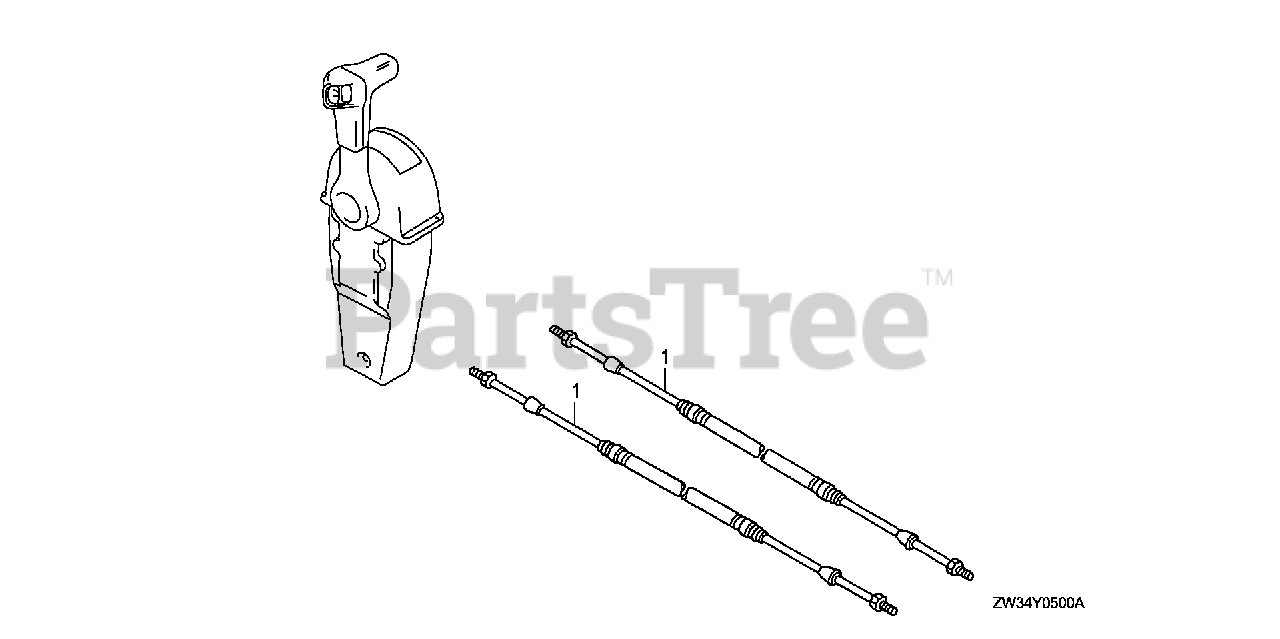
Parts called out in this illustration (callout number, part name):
1	CABLE, REMOTE CONTROL (10'') (LOW FRICTION)
1	CABLE ASSY., PUSH-PULL (33C-5FT)
1	CABLE, REMOTE CONTROL (11'') (LOW FRICTION)
1	CABLE ASSY., PUSH-PULL (33C-6FT)
1	CABLE, REMOTE CONTROL (12'') (LOW FRICTION)
1	CABLE ASSY., PUSH-PULL (33C-7FT)
1	CABLE, REMOTE CONTROL (13'') (LOW FRICTION)
1	CABLE ASSY., PUSH-PULL (33C-8FT)
1	CABLE, REMOTE CONTROL (14'') (LOW FRICTION)
1	CABLE ASSY., PUSH-PULL (33C-9F T)
1	CABLE, REMOTE CONTROL (15'') (LOW FRICTION)
1	CABLE ASSY., PUSH-PULL (33C-10FT)
1	CABLE, REMOTE CONTROL (16'') (LOW FRICTION) (NOT AVAILABLE)
1	CABLE ASSY., PUSH-PULL (33C-11FT)
1	CABLE, REMOTE CONTROL (17'') (LOW FRICTION)
1	CABLE ASSY., PUSH-PULL (33C-12 FT)
1	CABLE, REMOTE CONTROL (18') (LOW FRICTION) (NOT AVAILABLE)
1	CABLE ASSY., PUSH-PULL (33C-13 FT)
1	CABLE, REMOTE CONTROL (1 9'') (LOW FRICTION)
1	CABLE ASSY., PUSH-PULL (33C-14FT)
1	CABLE, REMOTE CONTROL (20'') (LOW FRICTION) (NOT AVAILABLE)
1	CABLE ASSY., PUSH-PULL (33C-15 FT)
1	CABLE, REMOTE CONTROL (21') (LOW FRICTION)
1	CABLE ASSY., PUSH-PULL (33C-16FT)
1	CABLE, REMOTE CONTROL (22') (LOW FRICTION) (NOT AVAILABLE)
1	CABLE ASSY., PUSH-PULL (33C-17 FT)
1	CABLE, REMOTE CONTROL (2 3'') (LOW FRICTION)
1	CABLE ASSY., PUSH-PULL (33C-18 FT)
1	CABLE, REMOTE CONTROL (24') (LOW FRICTION) (NOT AVAILABLE)
1	CABLE ASSY., PUSH-PULL (33C-19FT)
1	CABLE, REMOTE CONTROL (25') (LOW FRICTION)
1	CABLE ASSY., PUSH-PULL (33C-20FT)
1	CABLE, REMOTE CONTROL (26') (LOW FRICTION)
1	CABLE ASSY., PUSH-PULL (33C-21FT)
1	CABLE, REMOTE CONTROL (27') (LOW FRICTION)
1	CABLE ASSY., PUSH-PULL (33C-22FT)
1	CABLE, REMOTE CONTROL (28') (LOW FRICTION) (NOT AVAILABLE)
1	CABLE ASSY., PUSH-PULL (33C-23FT)
1	CABLE, REMOTE CONTROL (2 9') (LOW FRICTION)
1	CABLE ASSY., PUSH-PULL (33C-24FT)
1	CABLE, REMOTE CONTROL (30') (LOW FRICTION) (NOT AVAILABLE)
1	CABLE ASSY., PUSH-PULL (33C-25FT)
1	CABLE, REMOTE CONTROL (31') (LOW FRICTION)
1	CABLE ASSY., PUSH-PULL (33C-26FT)
1	CABLE, REMOTE CONTROL (32') (LOW FRICTION) (NOT AVAILABLE)
1	CABLE ASSY., PUSH-PULL (33C-27FT)
1	CABLE, REMOTE CONTROL (33') (LOW FRICTION)
1	CABLE ASSY., PUSH-PULL (33C-28FT)
1	CABLE, REMOTE CONTROL (34') (LOW FRICTION)
1	CABLE ASSY., PUSH-PULL (33C-29FT)
1	CABLE, REMOTE CONTROL (35') (LOW FRICTION)
1	CABLE ASSY., PUSH-PULL (33C-30FT)
1	CABLE ASSY., PUSH-PULL (33C-31FT)
1	CABLE ASSY., PUSH-PULL (33C-32FT)
